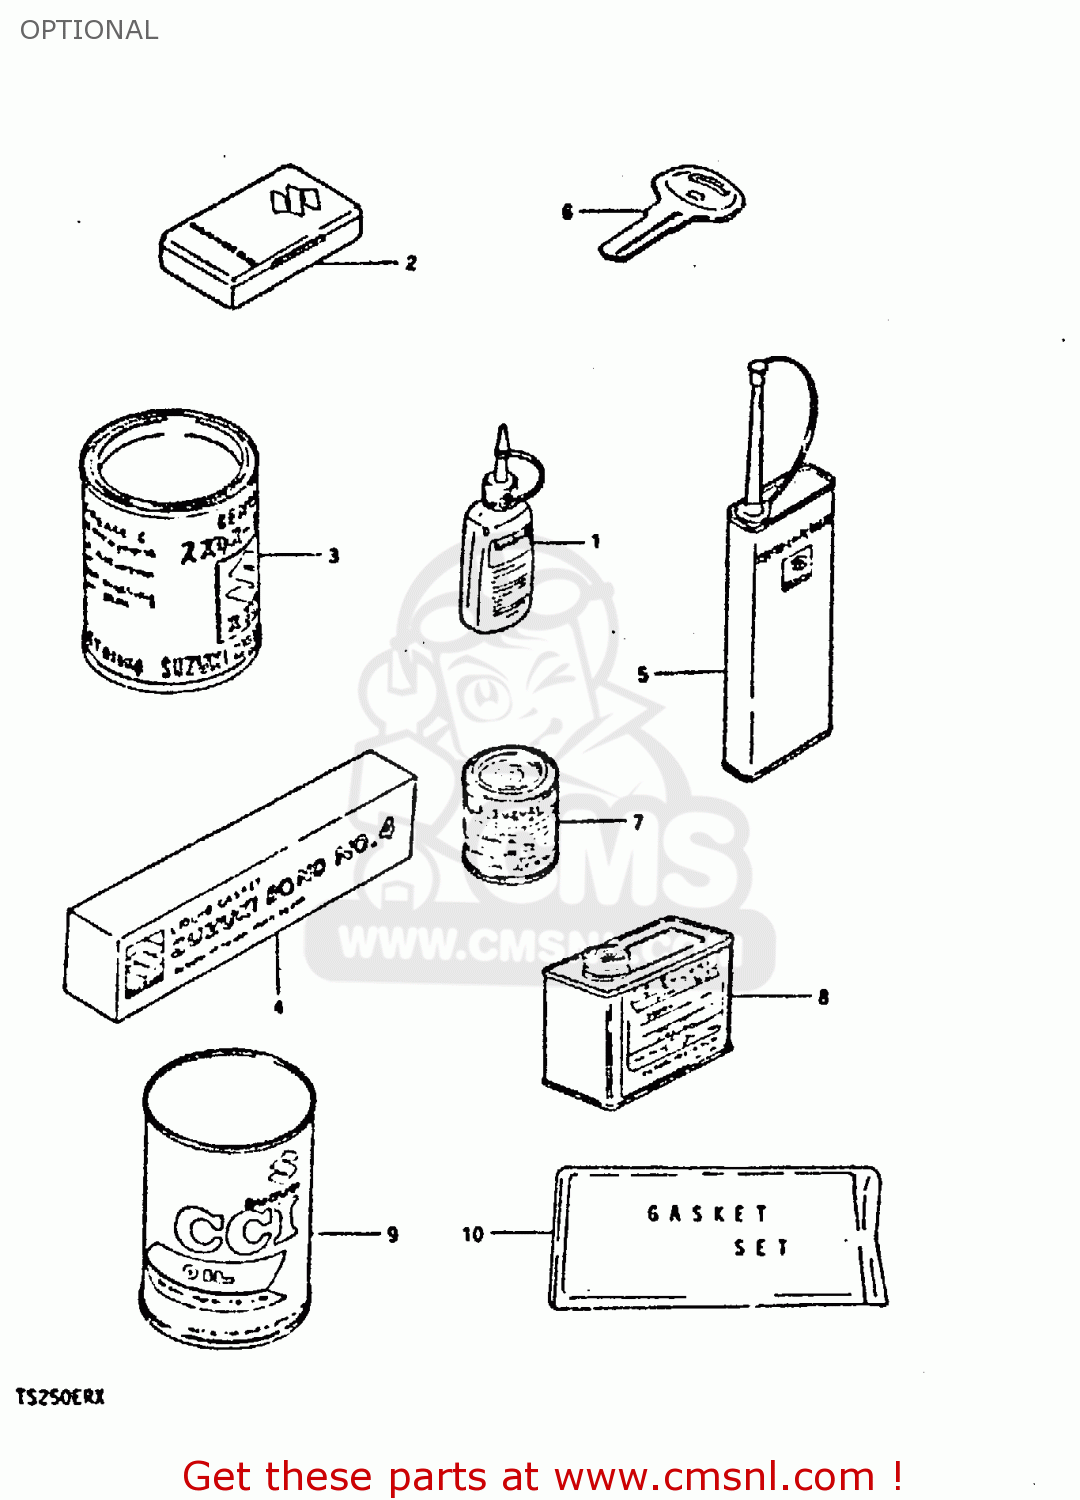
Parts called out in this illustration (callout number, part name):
1	THREAD LOCK NO.1303B PURPL 50G
2	TUBE REPARING TOOL
3	GREASE(C)EP2 LITHIUM 150G
4	LIQUID GSKT 150G BLACK
5	THREAD LOCK NO.1401 CLEAR 200G
6	KEY,BLANK
7	PAINT,BLACK
8	PAINT (BLACK)
9	CCI OIL
10	GASKET SET (MCA)
